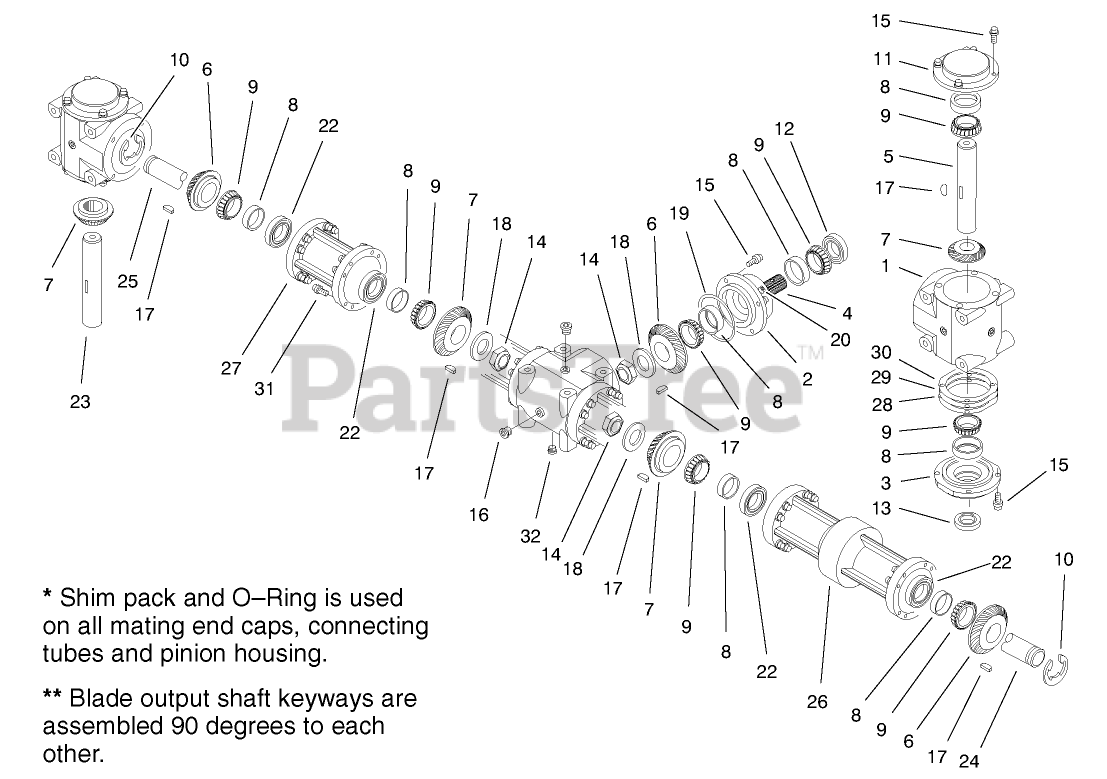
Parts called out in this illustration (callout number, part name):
2	HOUSING - PINION
3	CAP-END, OPEN
4	SHAFT - INPUT, SPLINED
5	SHAFT - CROSS, A/D
6	GEAR - 27 TOOTH
7	GEAR - 29 TOOTH
8	Bearing-Cup
9	Bearing-Cone
10	CLIP-RETAINING
11	CAP-END, CLOSED
13	SEAL
14	NUT-JAM
17	KEY-WOODRUFF
18	WASHER
19	O-RING
23	SHAFT - CROSS, B/D
24	SHAFT - CONNECTING, LONG
25	SHAFT - CONNECTING, SHORT
26	FLANGE - CONNECTING, LONG
27	FLANGE - CONNECTING, SHORT
28	SHIM-BROWN, .010IN
29	SHIM-BLUE, .005IN
30	SHIM-GREEN, .003IN
32	PLUG-MAGNETIC
